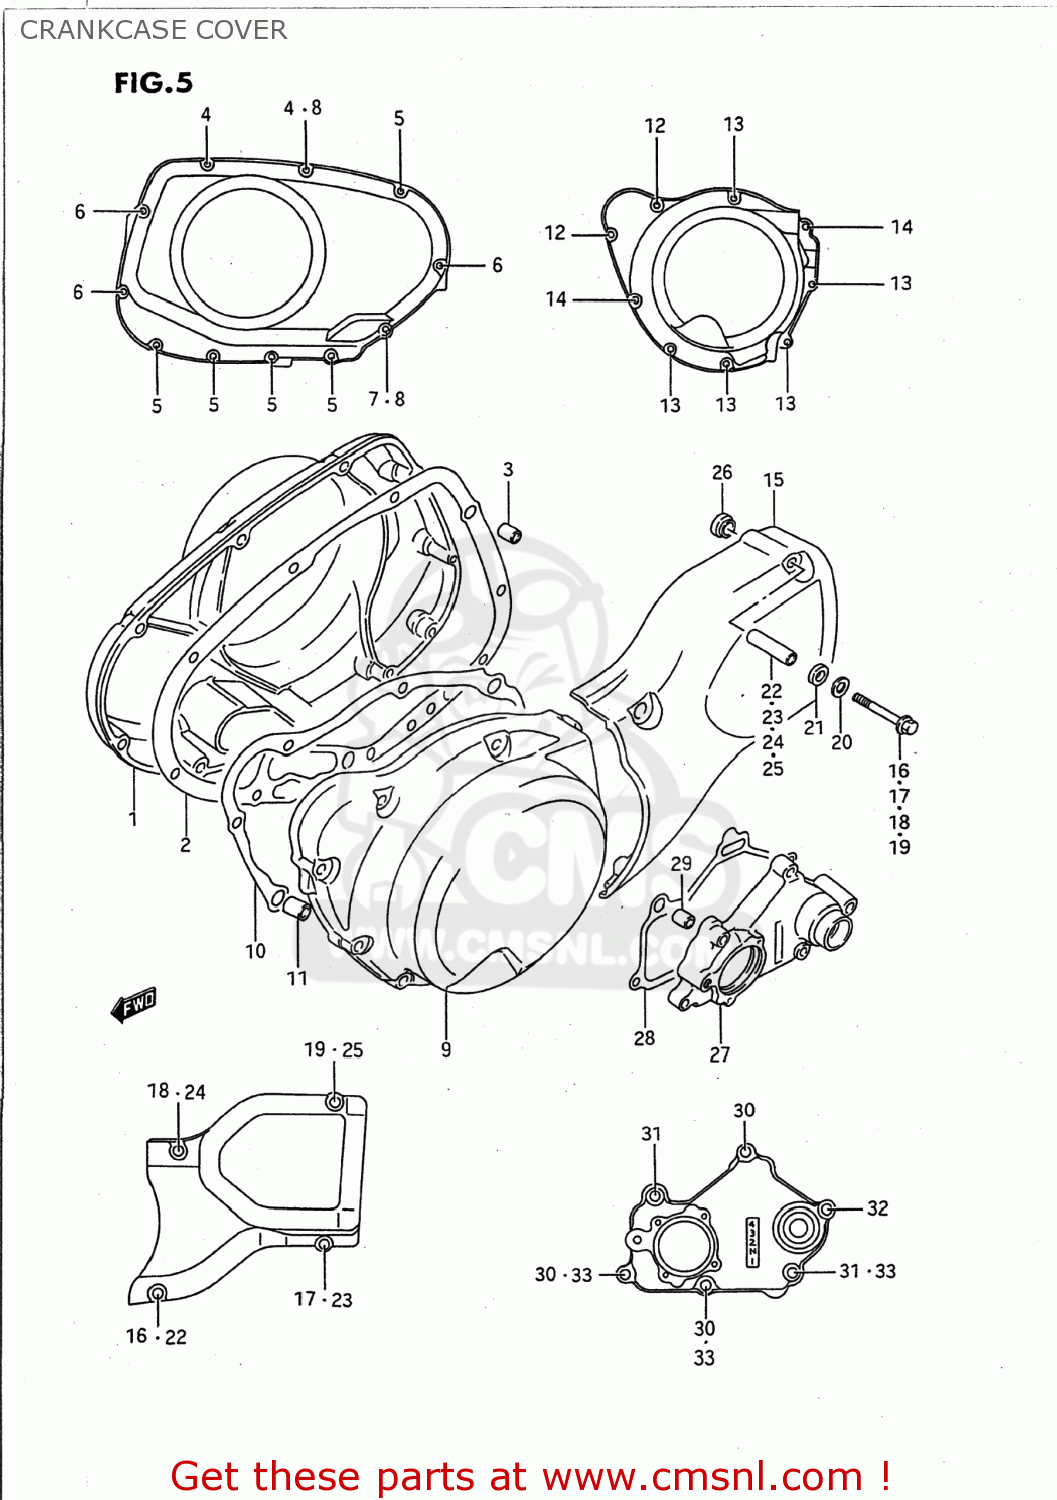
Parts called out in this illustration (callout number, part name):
1	COVER,CLUTCH
2	GASKET,CLUTCH COVER (NAS)
3	PIN
4	BOLT
5	BOLT
6	BOLT
7	BOLT
8	GASKET(5.8X13X1.2) (NAS)
9	COVER,GENERATOR
10	GASKET,MAGNETO COVER (NAS)
11	PIN (11X20)(SUS)
12	BOLT
13	BOLT
14	BOLT
15	COVER,SECONDARY GEAR CASE
16	BOLT
17	BOLT
18	BOLT
19	BOLT
20	WASHER
21	WASHER(8.7X15X2.1)
22	SPACER(6.1X9X18.2)
23	SPACER(6.1X9X23)
24	SPACER (L=43)
25	SPACER (L=45.9)
26	WASHER(8.7X16X5)
27	COVER,GEAR SHIFT
28	GASKET,GEAR SHIFT COVER (NAS)
29	PIN
30	BOLT
31	BOLT
32	BOLT
33	GASKET(5.8X13X1.2) (NAS)
